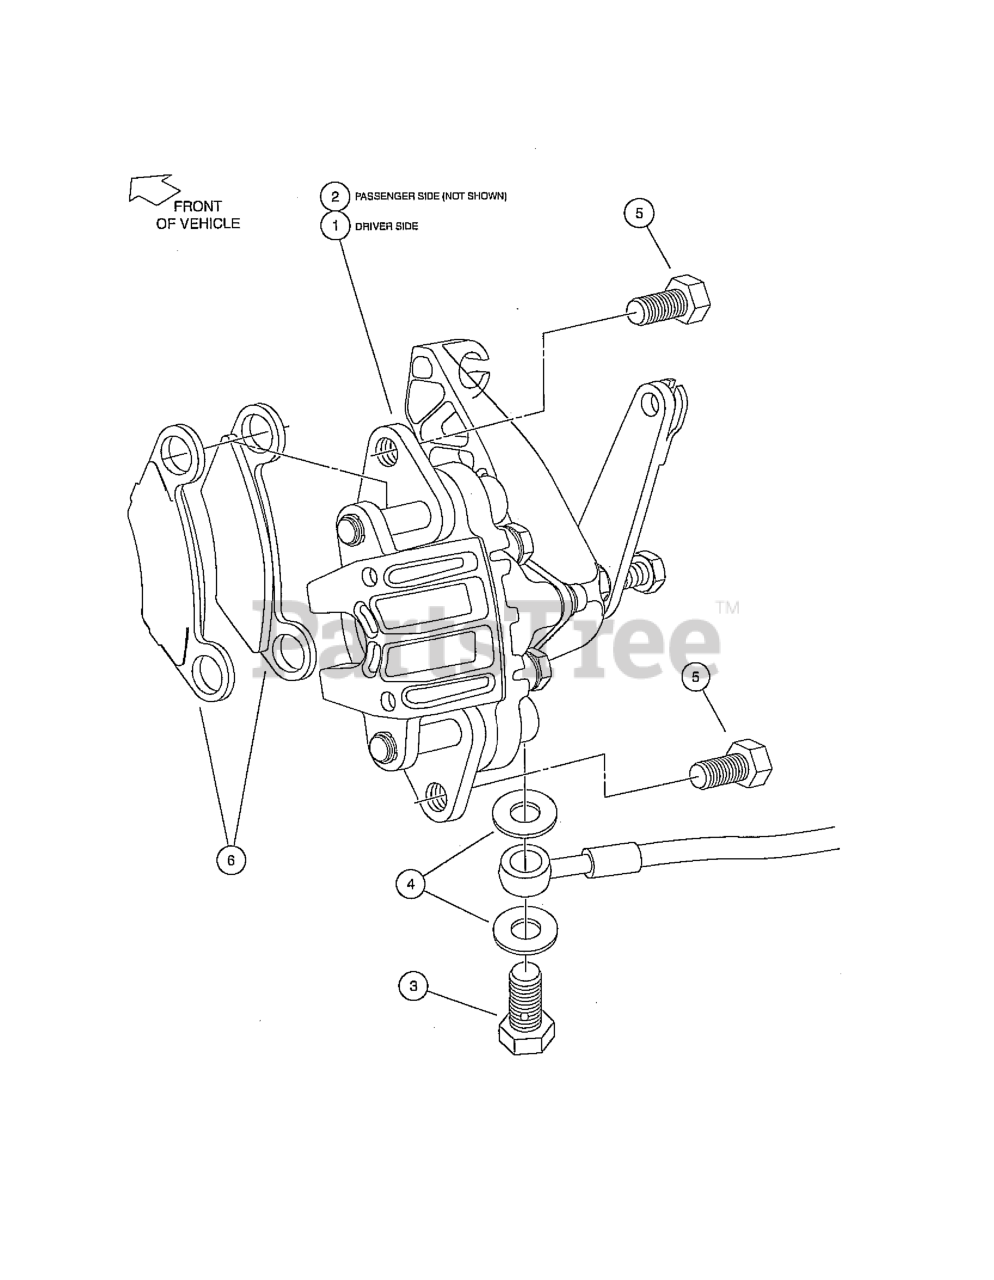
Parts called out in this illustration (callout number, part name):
1	CALIPER, BRAKE, HYDRO-MECH, LH
2	CALIPER, BRAKE, HYDRO-MECH, RH
3	BOLT, BANJO, M10X1X19
4	WASHER COPPER, M10 CRUSH
5	BOLT FLG, 3/8-24X.750 LOCTITE
6	SERVICE KIT, BRAKE PAD
